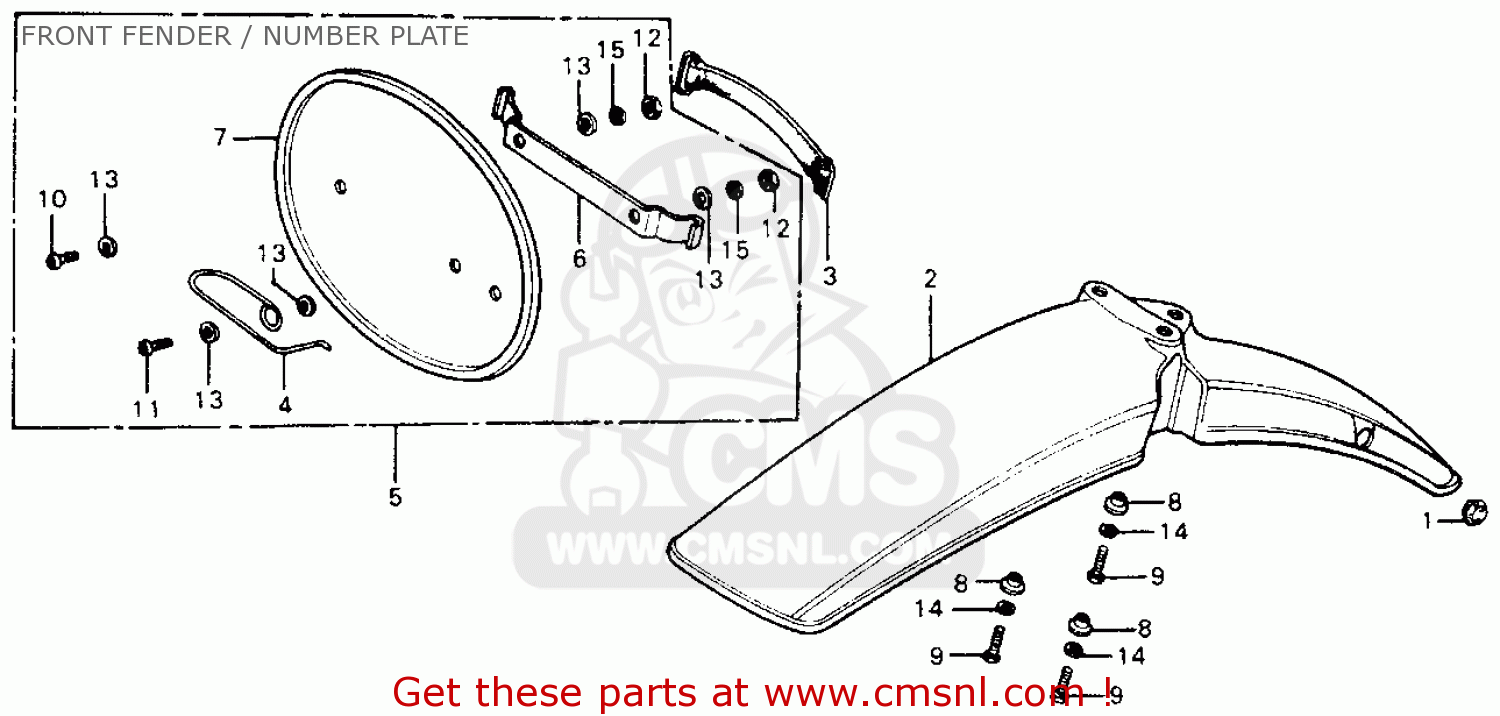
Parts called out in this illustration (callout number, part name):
1	PLUG,WELESS HOLE
2	FENDER,FR *R-23*
3	BAND,FR.NO.PLATE
4	GUIDE,CABLE
5	PLATE,FR.NO*NH-24
6	STAY,FR.NO.PLATE
7	PLATE,FRONT NO.
8	WASHER,CHAIN CASE
9	BOLT,HEX 6X12
10	SCREW,CROSS,5X12
11	SCREW,CROSS,5X16
12	NUT THIN 5MM
13	WASHER,PLAIN,5MM
14	WASHER PLAIN 6MM
15	WASHER,SPG.,5MM
